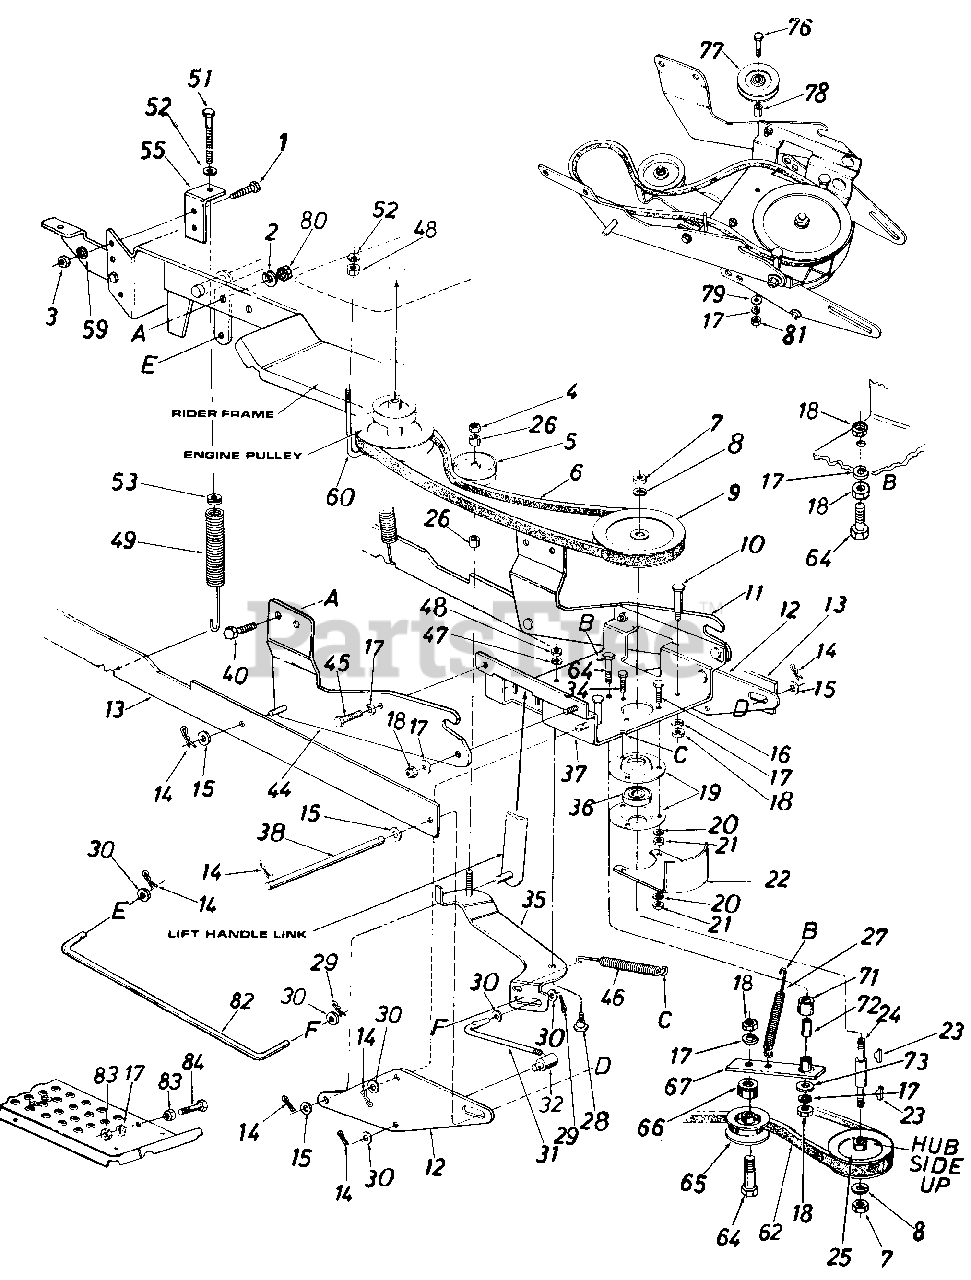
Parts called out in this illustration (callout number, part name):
1	Hex Bolt 1/4-28 x 1.00" Lg. Grade 5
2	L.-Wash. 1/4" I.D.*
3	Hex Nut 1/4-28 Thd.*
4	Hex Cent. L-Nut 3/8-16 0 Thd.
5	Idler Pulley
6	"V" Belt
7	Hex Jam Nut 5/8-11 Thd.
8	L.-Wash. 5/8" I.D.*
9	6.50" O.D. x 5/8 Pulley
10	Shoulder Bolt
11	Channel Support Brkt.-R.H.
12	Linkage Brkt.
13	Linkage Arm Ass'y.
14	Intern. Cotter Pin .50 Dia.*
16	Hex Bolt 5/16 x 1.25" Lg.
17	L.-Wash. 3/8" I.D.*
18	Hex Jam Nut 3/8-16 Thd.
19	Bearing Housing
20	L.-Wash. 5/16" I.D.*
21	Hex Nut 5/16-18 Thd.*
24	Pulley Spindle
25	5/8 Pulley-6.28 I.D. x 5.56 O.D.
26	Spacer.383 I.D. x .503 O.D. x .562 Lg.
27	Extension Spring .54 O.D. x 5.25"
28	Shoulder Bolt
29	Cotter Pin 3/32" Dia.
31	Control Rod
32	Ferrule
34	Hex Sems Scr. 5/16-18 x .75" Lg.*
35	Clutch Idler Brkt. Ass'y.
36	Ball Bearing
37	Channel Ass'y.
38	Lift Handle Shaft
40	Hex Self-Tap Scr. 1/4-20 x .75" Lg.
44	Channel Supporting Brkt.-L.H.
45	Hex Bolt 3/8-16 x 1.0" Lg.
46	Extension spring
47	L.-Wash. 5/16" I.D.
48	Hex Nut 5/16-18 Thd.
49	Helper Spring
51	Hex Scr. 5/16-18 x 2.0" Lg. Special
52	Bell Wash. .345 I.D. x .88 O.D. x .06
53	Spring Insert
60	J.-Bolt 5/16-18 Thd.
62	"V"Belt 1/2 "A" x .89" Lg.
64	Hex Bolt 3/8-16 x 2.0" Lg.
65	Idler Pulley
66	Spacer.385 I.D. x .503 O.D. x .562" Lg.
67	Idler Arm Ass'y.
71	Spacer .380" I.D.
72	Spacer .3775 I.D. x .60 O.D. x 8.3 Lg.
73	Fl.-Wash. 3/8 I.D. x 1" O.D. x 1.27
76	Hex Bolt 3/8-16 x 2.5" Lg. (Grade 5)
77	Idler Pulley .38 I.D. x 3.06 O.D.
78	Spacer .385 I.D. x .630 O.D. x .76 Lg.
79	Fl.-Wash. .39 I.D. x 1-3/4 O.D. x 3/16"
80	Hex L-Nut 1/4-20 Thd.
81	Hex Nut 3/8-16 Thd.
82	Clutch Control Rod
83	Hex Nut 3/8-24 Thd.*
84	Hex Bolt 3/8-24 x 2.25" Lg.
